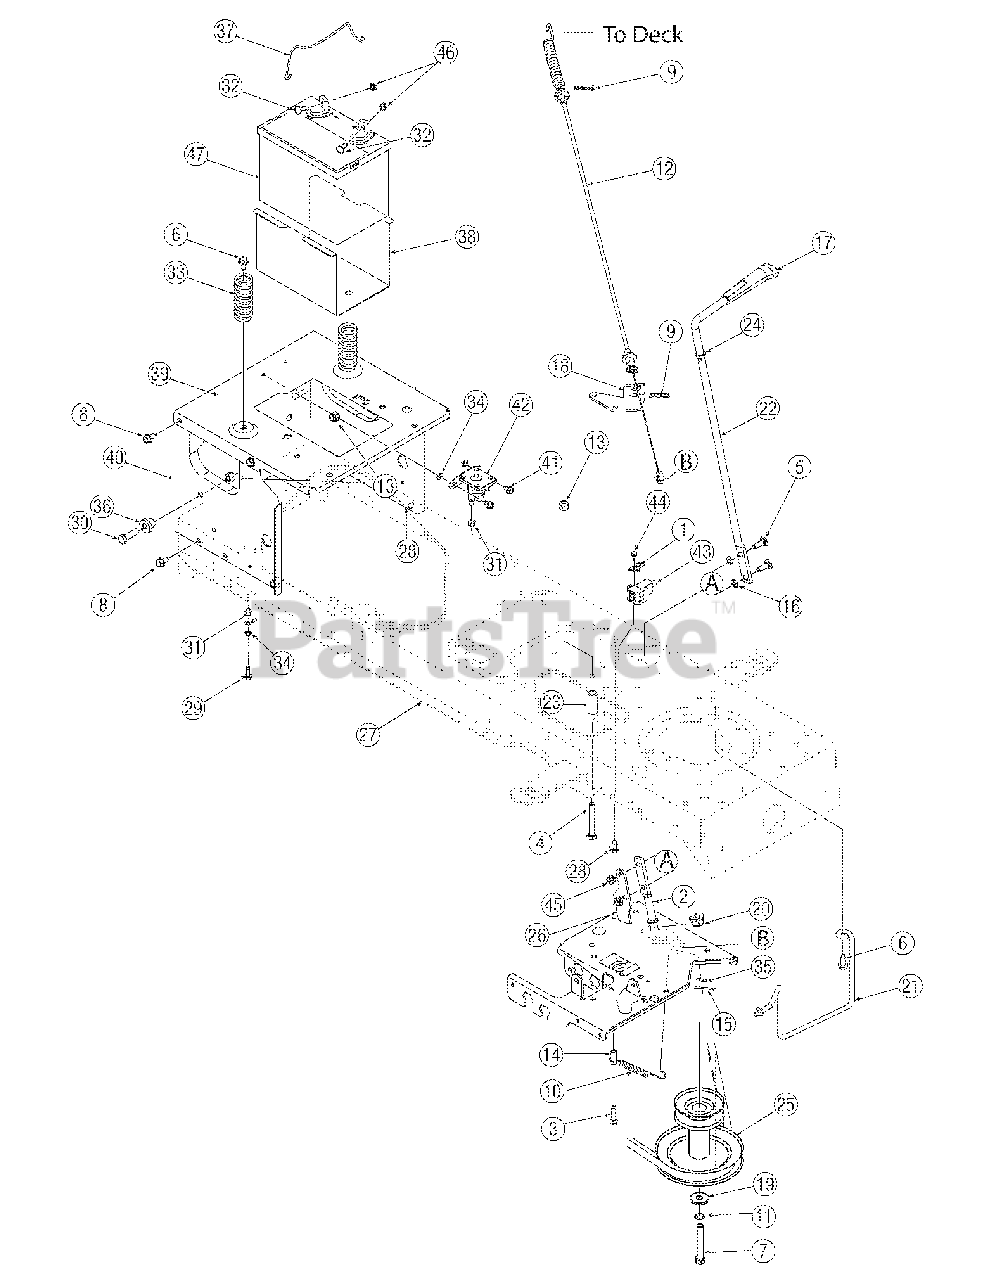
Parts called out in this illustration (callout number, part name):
1	Plate, Switch
2	Lever Assembly, Engagement
3	Screw, 1/4-20 x 1.500
4	Screw, 3/8-16, 2.50
5	Screw, Carriage, 5/16-18, 1.00
6	Screw, 5/16-18 x.750
7	Screw, 7/16-20, 3.25, Gr5
8	Screw, 5/16-12, 0.750
9	Click Pin
10	Extension Spring,.38OD x 3.9LG
11	Lock Washer, 7/16
12	Deck Engagement Cable
13	Nut, Flange Lock, 3/8-16, GrF
14	Spacer,.260 x.372 x 1.030LG
15	Pin, Cotter, 1/8 x 1.25
16	Nut, Speed,.3125 ID
17	Knob, PTO
20	Bearing, Flange, .500 ID
21	Keeper Rod, Belt
22	Engagement Handle, Deck
23	Spacer,.385 ID x.635 OD x 1.54
24	Flat Washer, .510 x .750 x .033
25	Pulley, Engine, 3.39 x 6.12 Dia
29	Screw, 1/4-20, 0.750
30	Screw, 3/8-16, 1.25, Gr5
31	Nut, Flange Lock, 1/4-20,
32	Screw, Carriage, 1/4-20,.75
33	Spring, Compr. , 1.28 OD
34	Washer, Lock, 1/4, External
35	Flat Washer, .344 x .688
36	Spacer, Shoulder,.38 x 1.0
37	Hold Rod, Battery
42	Solenoid, 12V, 100 Amp
43	Switch, Interlock
44	Screw, #10-16,.50
45	Nut, Flange, Lock Nut, 5/16-18
46	Nut, Sems, 1/4-20
47	Battery, 190 CCA
47	Battery, 235 CCA
